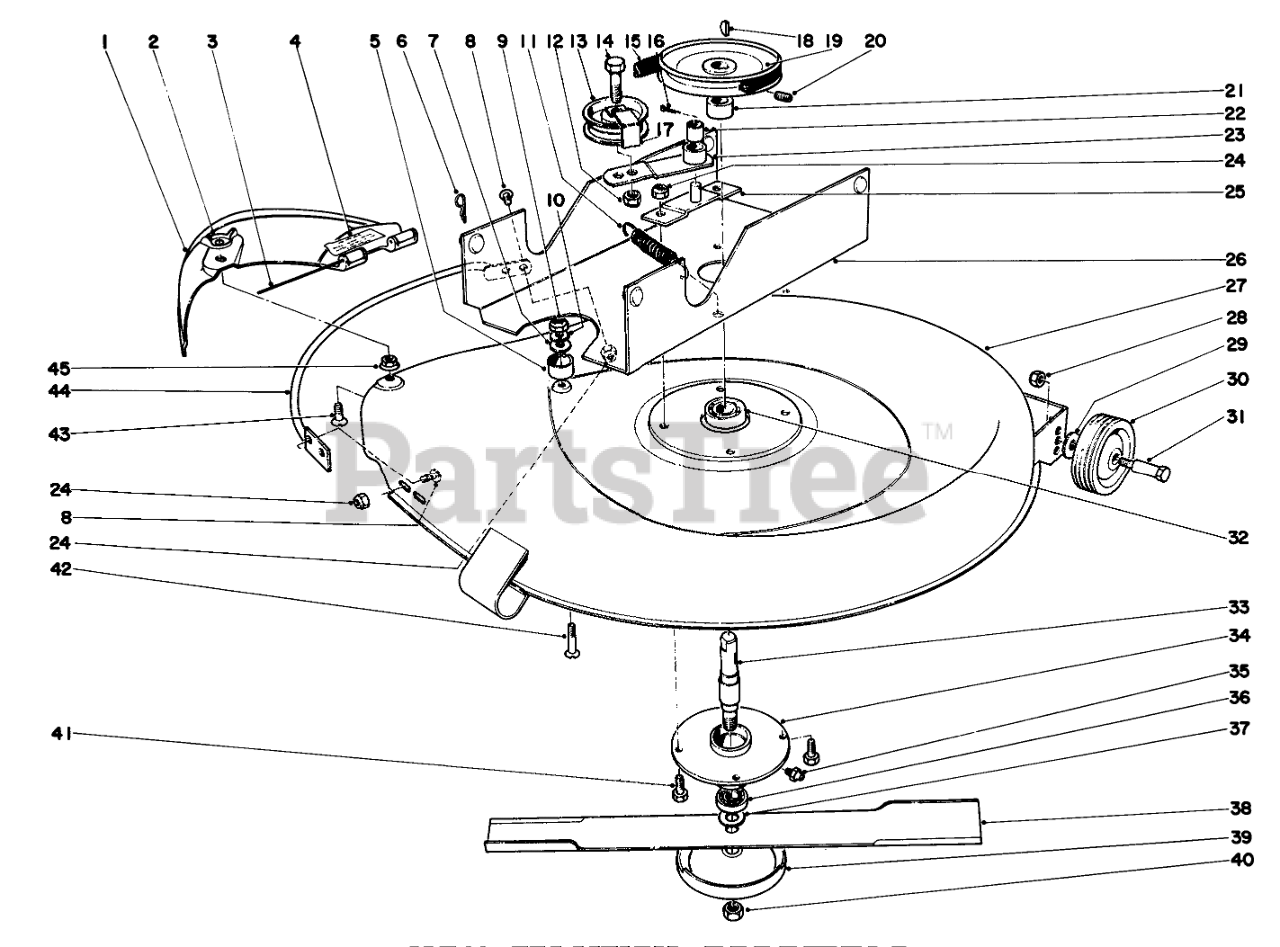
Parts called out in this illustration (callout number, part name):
1	DEFLECTOR
2	Wing Nut
3	Hinge Pin
4	Decal
5	Spacer
6	PIN-COTTER
7	WASHER-FLAT
8	5/16-18X5/8 TRS HD MS
9	NUT-HEX
10	WASHER-LOCK
11	Spring
12	NUT-LOCK, CONE
13	Idler Pulley
14	SCREW-HH
15	FRONT PULLEY BELT
16	PIN-COTTER
17	Belt Retainer
18	KEY-WOODRUFF
19	PULLEY
20	SCREW-HSH
21	Spacer
22	BUSHING
23	Idler Plate Incl. Ref. #22
24	NUT-LOCK, CONE
25	Pivot Bracket
26	Channel
27	Housing
28	NUT-LOCK, CONE
29	WASHER-FLAT
30	Wheel
31	Shoulder Bolt
32	Bearing
33	Blade Spindle
34	MOWER SPINDLE HOUSING
35	FITTING-GREASE
36	.6693 RP BALL BEARING
37	WASHER
38	Blade
39	Cup
40	NUT-LOCK, CONE
41	SCREW-HH
42	Screw
43	5/16-18X7/8 FLT HD MS
44	Blade Guard
45	PAL NUT
